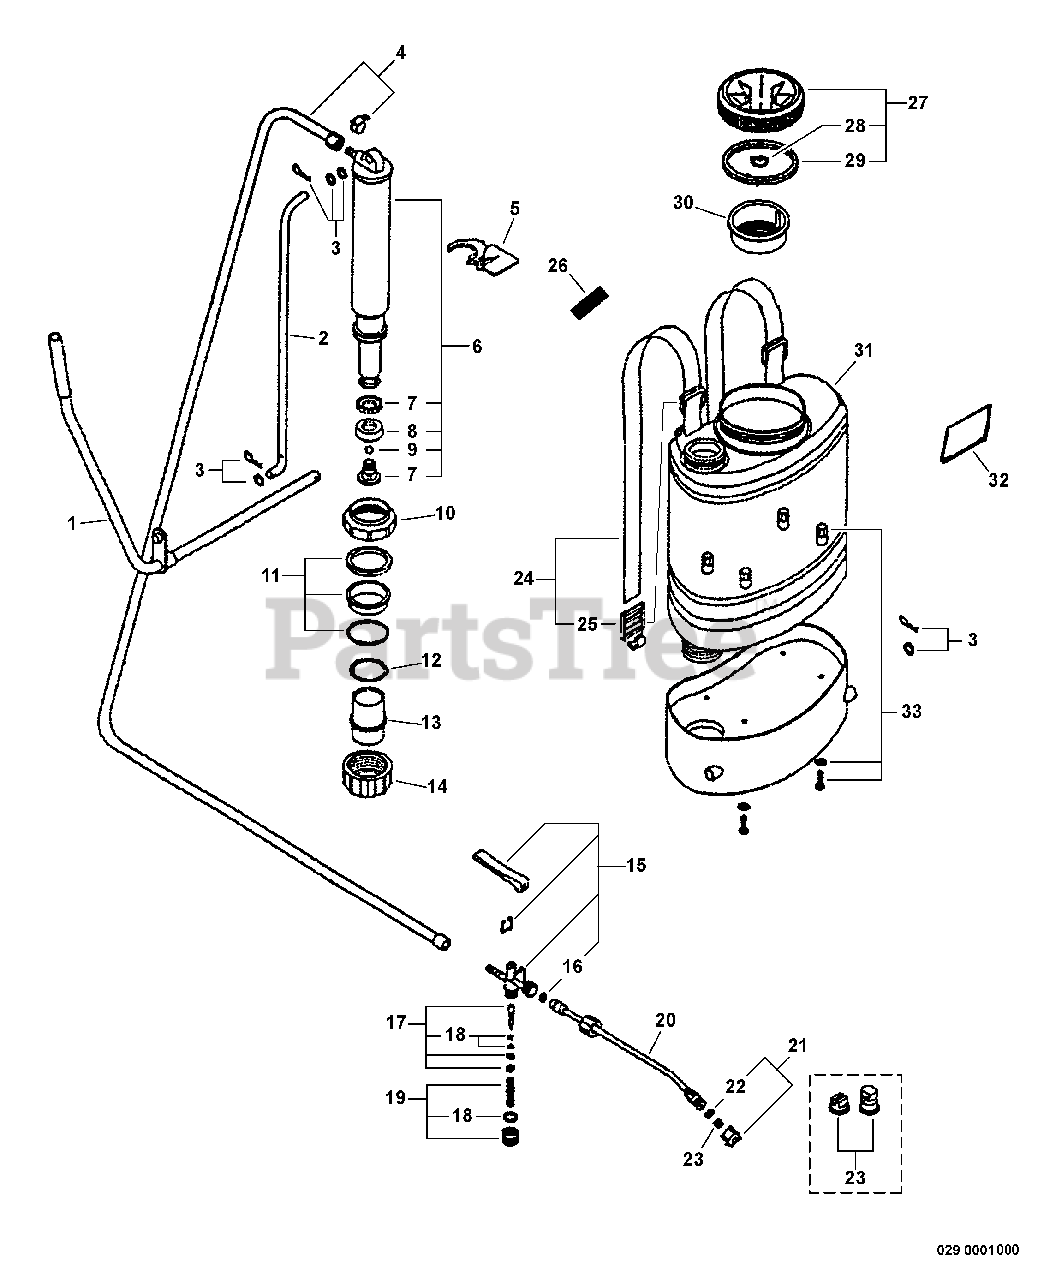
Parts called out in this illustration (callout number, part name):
1	HANDLE, PUMP
2	PUMP LEVER ASSY
3	PIN KIT
5	AGITATOR
6	PUMP ASSY
7	RING SEALING KIT
8	CUP, PISTON
9	BALL - PLASTIC
10	CAP, PUMP
11	GUIDE, SEAL
12	O-RING
13	CYLINDER
14	CAP, BOTTOM
15	SPRAY PISTOL ASSY
16	WASHER
17	SPINDLE SET
18	O-RING KIT
19	SEAL KIT
20	SPRAY WAND - ALUMINUM
21	NOZZLE HOLDER KIT
22	WASHER
23	SPRAY TIP SET
24	STRAP ASSY
26	LABEL - CAUTION
27	CAP ASSY
28	VALVE, CHECK
29	SEAL, CAP
30	STRAINER, DEBRIS
31	TANK
32	LABEL - CAUTION
33	TANK BASE ASSY
